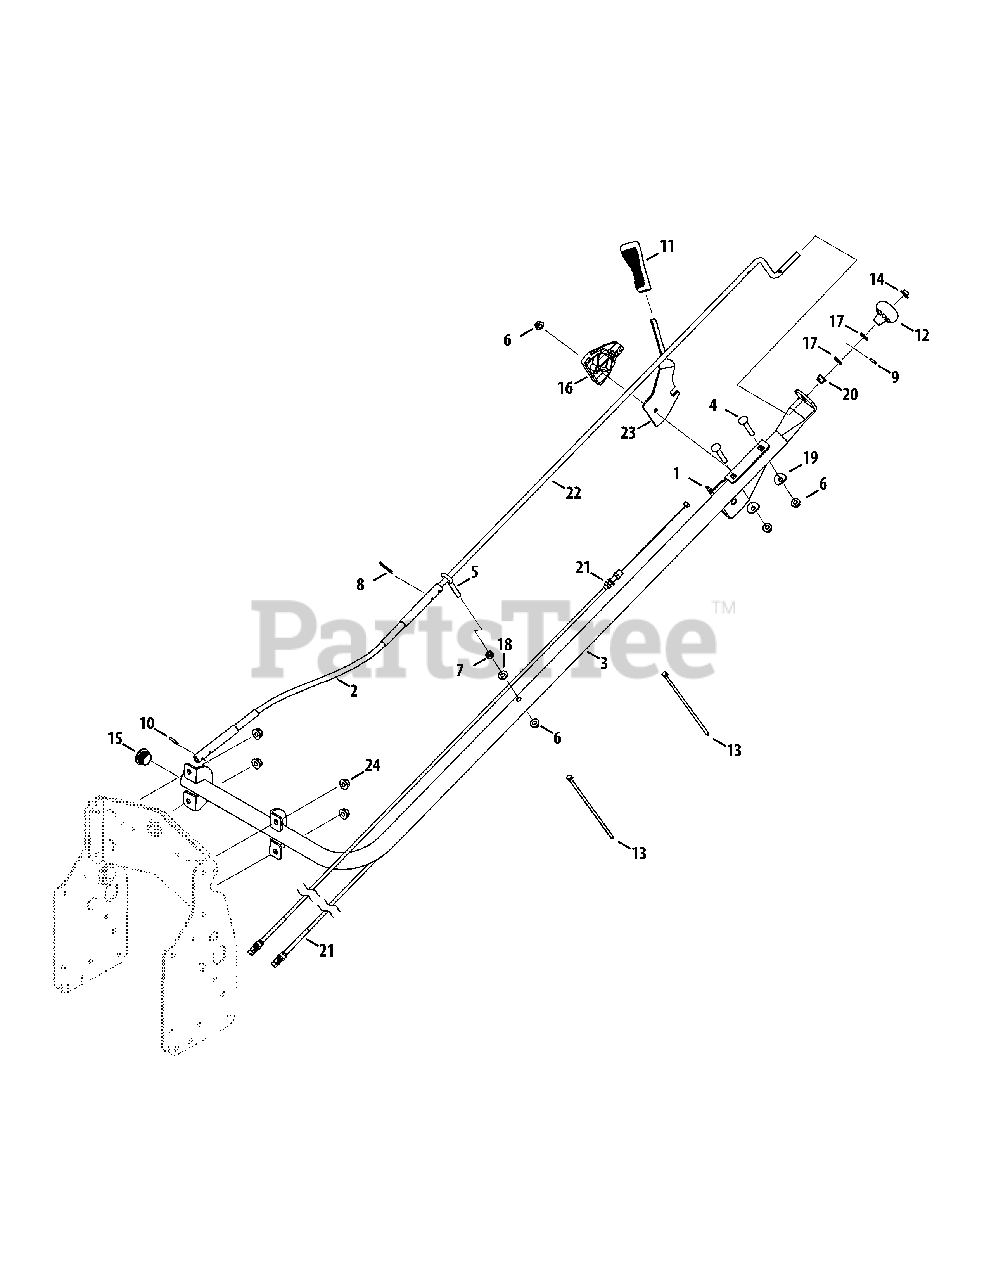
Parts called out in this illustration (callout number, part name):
1	Tilt Assembly
2	Control Assembly
3	Bracket Assembly
4	Carriage Screw, 5/16-18 x 2.00
5	Eye Bolt, 5/16-18 x 3.25
6	Flange Lock Nut, 5/16-18
7	Hex Nut, 5/16-18
8	Cotter Pin, .08 x 1.42
9	Roll Pin, 1/8 x .63
10	Spring Pin, .156 x .875
11	Handle Grip, 3/8
12	Shift Knob, .390
13	Cable Tie, 3/16 x .05 x 7.4
14	Push Cap, 3/8
15	Plug, 1.250
16	Chute Tile Cable Guide
17	Flat Washer, .375 x .738 x .063
18	Flat Washer, .344 x .688 x .065
19	Saddle Washer, .320 x .930 x .060
20	Snap Flange Bearing, .385
21	Chute Deflector Cable, 74.5
22	Chute Crank, .375 x 34.63
23	Chute Tilt Bracket Handle
24	Flange Lock Nut, 3/8-16
